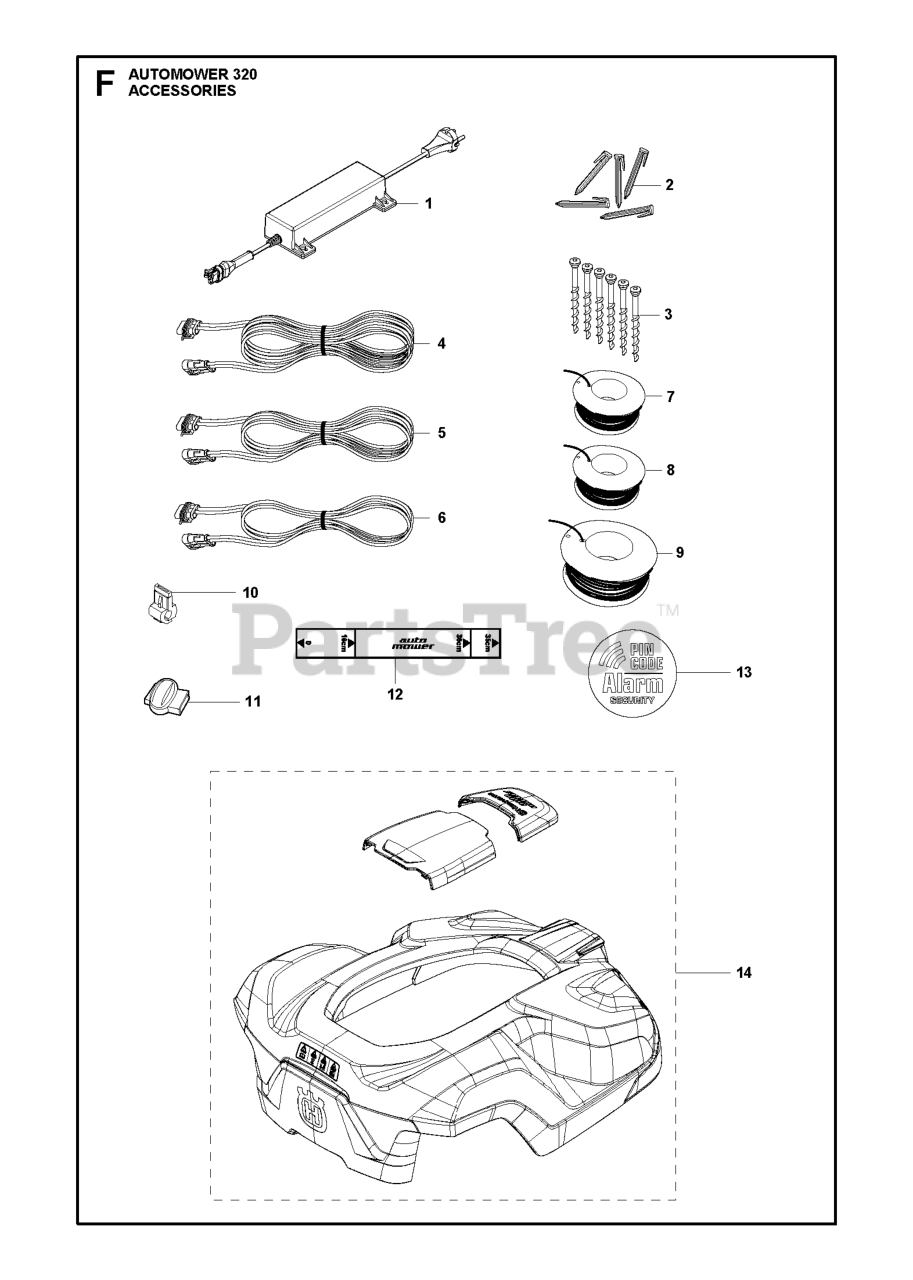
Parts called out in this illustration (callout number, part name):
2	BLADE KIT HUSQVARNA 9 PCS 50HR
2	BLADE SET 45 PCS
2	BLADE SET 300 PCS. CARBON STEE
3	DVD AUTOCHECK EXP SERVICE
4	LABEL WARRANTY SEAL DEALER
4	LABEL WARRANTY SEAL KIT 10 PK
5	TEST EQUIPMENT
6	CABLE WHITE ALT GREY
9	STICKER CABLE MARKERS KIT 10PC
14	REAR WHEEL KIT W/ BRUSHES
16	DECAL.HUSQVARNA.210MM
17	KIT LID - AUTOMOWER HOUSE
18	COVER BASE P2 HOUSE
20	HANDLE RELEASE LEFT
23	SPRING SPRING CAP
25	SCREW 14MM
26	HINGE PIN
27	HANDLE RELEASE RIGHT
28	SUPPORT BASE LEFT
29	NUT
30	SUPPORT BASE RIGHT
31	SCREW IHPANM M6X25 4.6 ZP-BC
32	430/450 HOUSE KIT
